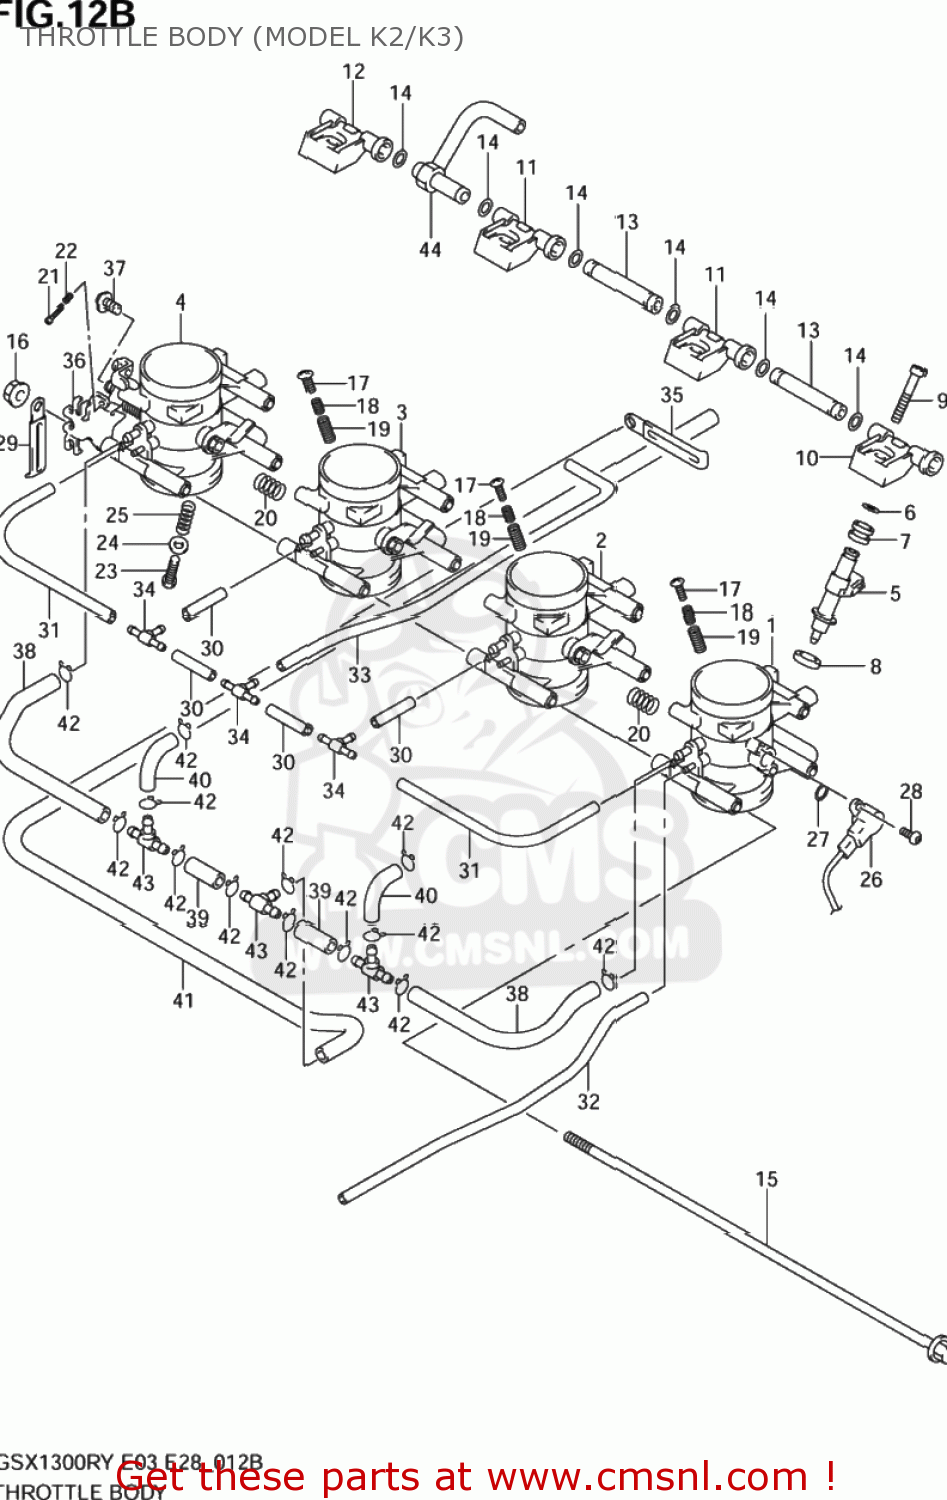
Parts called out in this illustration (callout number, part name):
1	THROTTLE BODY ASSY,L
2	THROTTLE BODY ASSY ML
3	THROTTLE BODY ASSY MR
4	THROTTLE BODY ASSY,R
5	INJECTOR ASSY
6	O RING
7	RING,CUSHION
8	RING,SEAL
9	SCREW
10	JOINT,NO.1
11	JOINT,NO.2,3
12	JOINT,NO.4
13	JOINT
14	O RING
15	BOLT
16	NUT
17	SCREW,STOP
18	SPRING
19	SPRING
20	SPRING
21	SCREW
22	SPRING
23	SCREW,STOP
24	WASHER
25	SPRING
26	SENSOR ASSY,TH
27	O RING
28	SCREW
29	CLAMP
30	HOSE,RUBBER(L:35)
31	HOSE,RUBBER(L:100)
32	HOSE,RUBBER(L:200)
33	HOSE,RUBBER(L:230+20)
34	JOINT
35	BAND
36	PLATE,STAY
37	SCREW
38	HOSE,RUBBER(L:80+25)
39	HOSE,RUBBER(L:35)
40	HOSE,RUBBER(L:30+30)
41	HOSE,RUBBER(L:440+30)
42	CLIP
43	JOINT
44	JOINT
